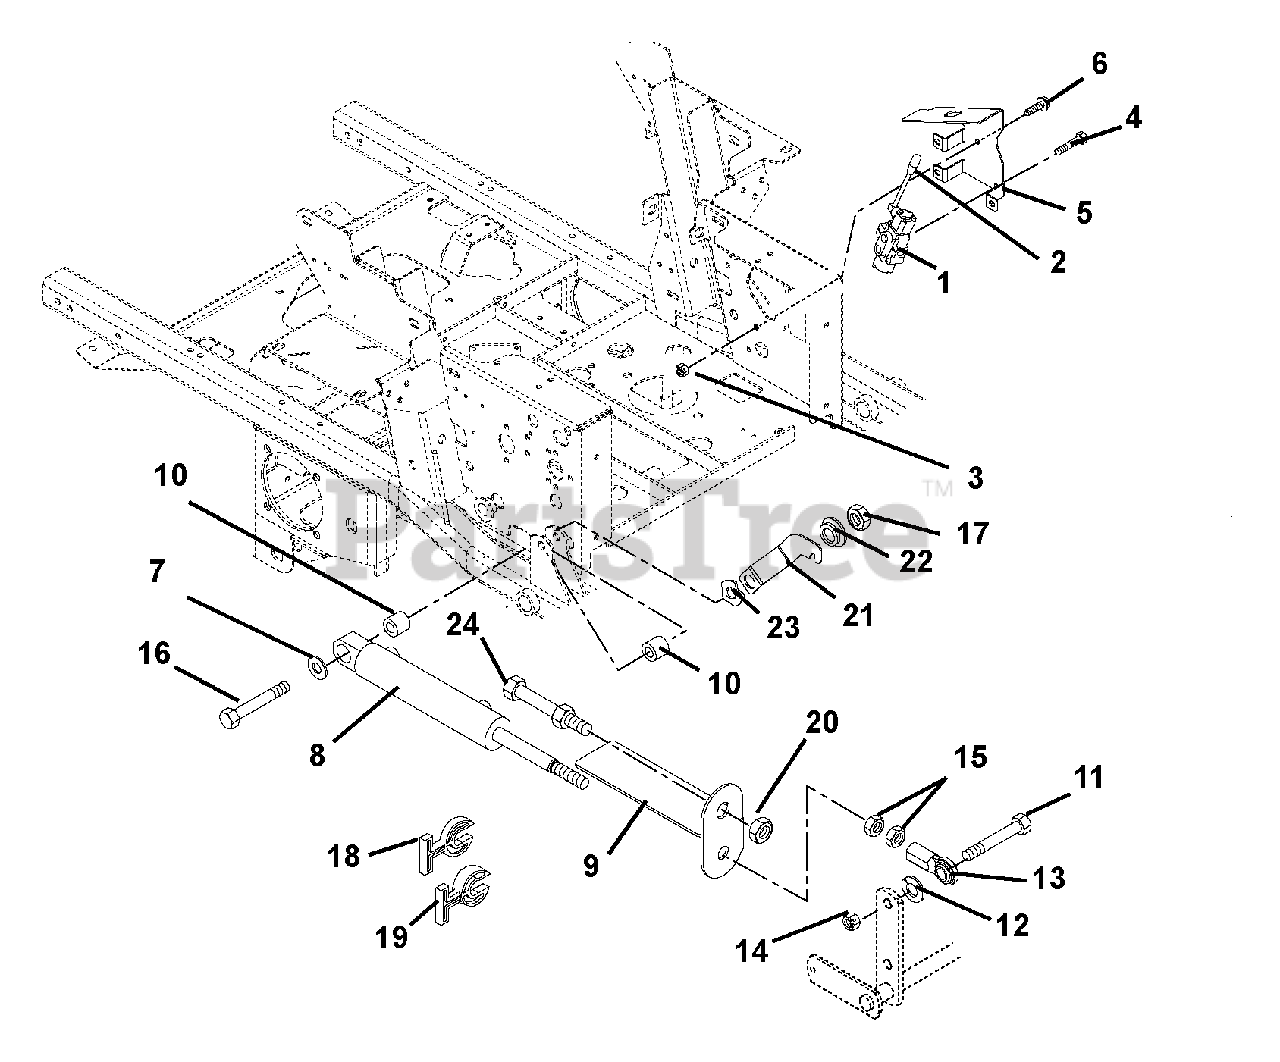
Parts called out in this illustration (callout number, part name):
1	Valve, Hydraulic
2	Knob (Service Only)
3	Nut, Locking Top Flange .31-18
4	Bolt, Hex .31-18 x 2.5 Grade 5
5	Bracket, Valve Mounting
6	Screw, Tapping .38-16 x .50 Hex Washer Head
7	Washer, Flat Steel .515 x 1.625 x .25
8	Cylinder, Hydraulic Lift
9	Strap, Cut Indicator / Guard
10	Bushing .5/6 x 1.00 x 1.05
11	Bolt, Hex .62-11 x 2.25 Grade 8
12	Washer, Lock .62 x .156
13	Rod End, Right Hand Female .625
14	Nut, Locking Center .62-11
15	Nut, Jam .625-18
16	Bolt, Hex .50-13 x 3.75 Grade 5
17	Nut, Locking Top Flange .50-13
18	Stop, Cylinder .34 Thick
19	Stop, Cylinder .68 Thick
20	Nut, Jam .75-16
21	Latch, Footboard
22	Bushing, Flange .515 x .75 x .275 x 1.12
23	Washer, Wave .076 x 1.12 x .08
